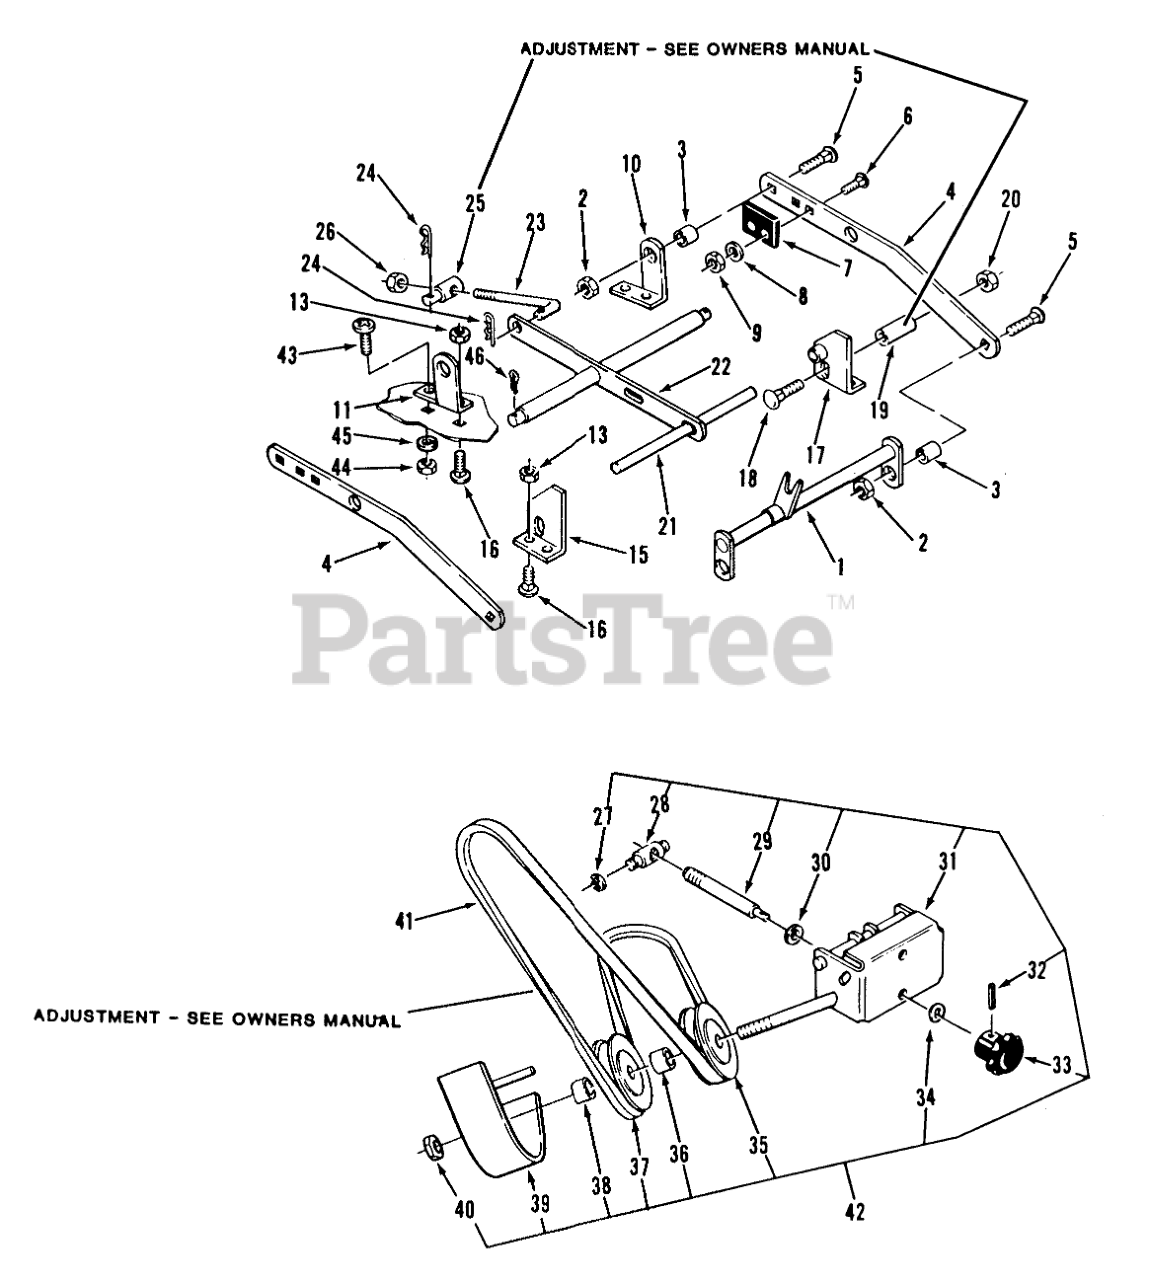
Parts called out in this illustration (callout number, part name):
1	Hitch
2	LOCKNUT-FLANGE
3	SPACER
4	Bar Draft
5	Bolt
6	Bolt-Carriage
7	BUMPER
8	Collar
9	Nut
10	LH Rear Bracket
11	Rear Bracket RH
13	Nut
15	Front Bracket RH
16	Bolt-Carriage
17	Front Bracket LH
18	CARRIAGE BOLT -4
20	Nut
21	Front Shaft
22	Leveler
23	ROD-LEVEL ADJUST
24	Hairpin
25	TRUNNION-LIFT
26	NUT
27	RING-RETAINING
28	TRUNNION-DOUBLE
29	ROD ADJ
30	Washer
31	Front Support
32	PIN-ROLL
33	KNOB-ADJUSTMENT
34	WASHER-SPRING
35	Pulley-V
36	SPACER
37	PULLEY-FLAT IDLER
38	SPACER-OUTER
39	Belt Cover
40	Nut
41	V-BELT
42	ASM-SUPPORT,IDLER
43	PAN HEAD SCREW-4
44	Nut
45	LOCKWASHER
46	Cotter Pin
